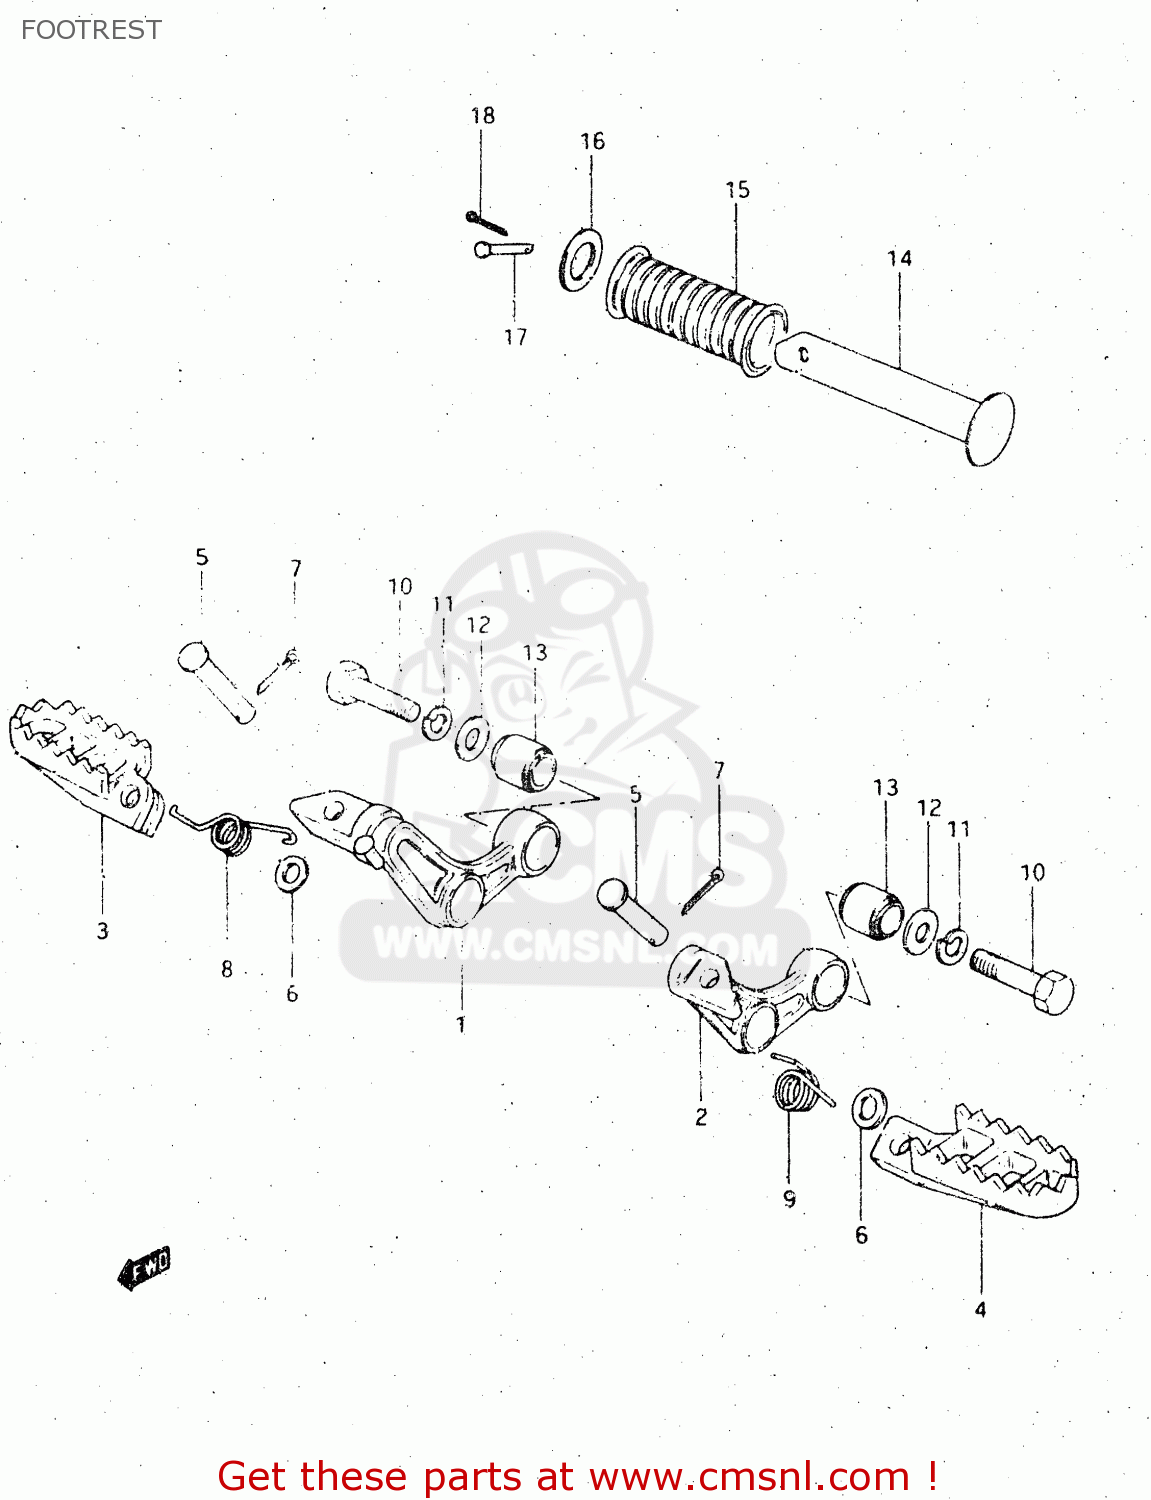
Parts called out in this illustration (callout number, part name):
1	BAR,FRONT FOOTREST
2	BAR,FRONT FOOTREST,LEFT
3	FOOTREST,RIGHT
4	FOOTREST
5	PIN
6	WASHER
7	PIN 20X20
8	SPRING
9	SPRING
10	BOLT
11	LOCK WASHER
12	WASHER (10.1X21X2.3)
13	BUSH
14	BAR,PILLION FOOTREST
15	RUBBER,PILLION FOOTREST
16	WASHER (19.5X32X2)
17	PIN
18	COTTER PIN
